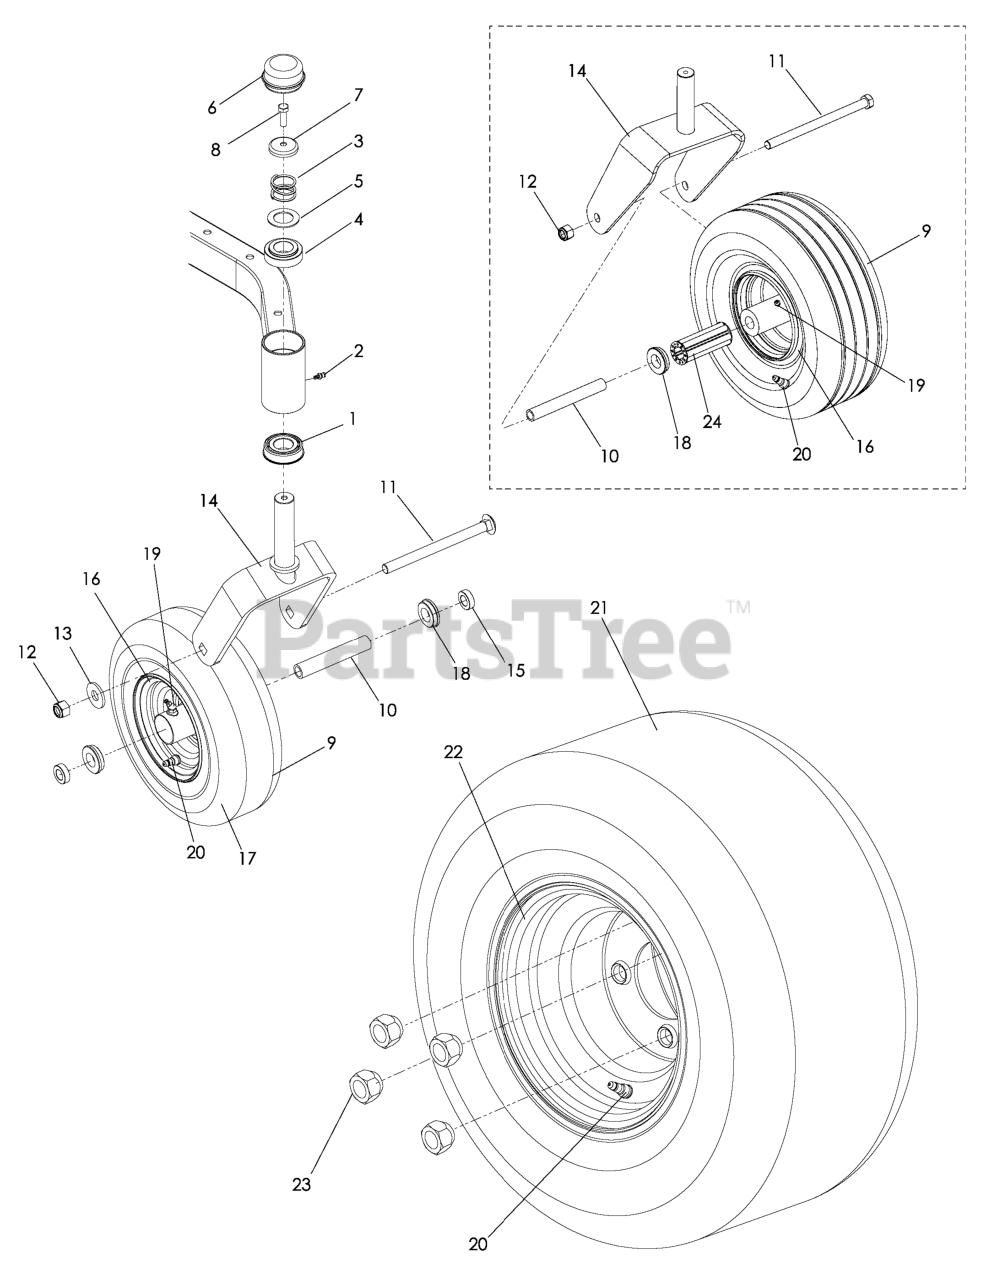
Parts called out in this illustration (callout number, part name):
1	BEARING FLANGED
2	ZERK, 3/16, DRIVE IN
3	SPRING, CASTER
4	BUSHING, CASTER
5	WASHER, 1.025 ID X 1.64
6	GREASE CAP
7	CASTER.PLUG
8	HCS 5/16C X 1
9	TIRE COMPLETE
11	RHSNB 1/2-13 X 6.50 GR2 ZD
12	NUT 1/2-13 HEX NYLOC ZD
13	WASH USS FLAT 1/2
14	YOKE.CASTER.ORANGE
15	SPACER, 5/16"
17	TIRE - CASTER
18	BEARING RETAINER
19	ZERK
20	VALVE STEM TR-412
21	TIRE/WHEEL.ASM.22X9.5-10
22	RIM.8X7.W/8".OFFSET.SILVER.ZTR
23	LUG NUT 1/2F
24	ROLLER BEARING
